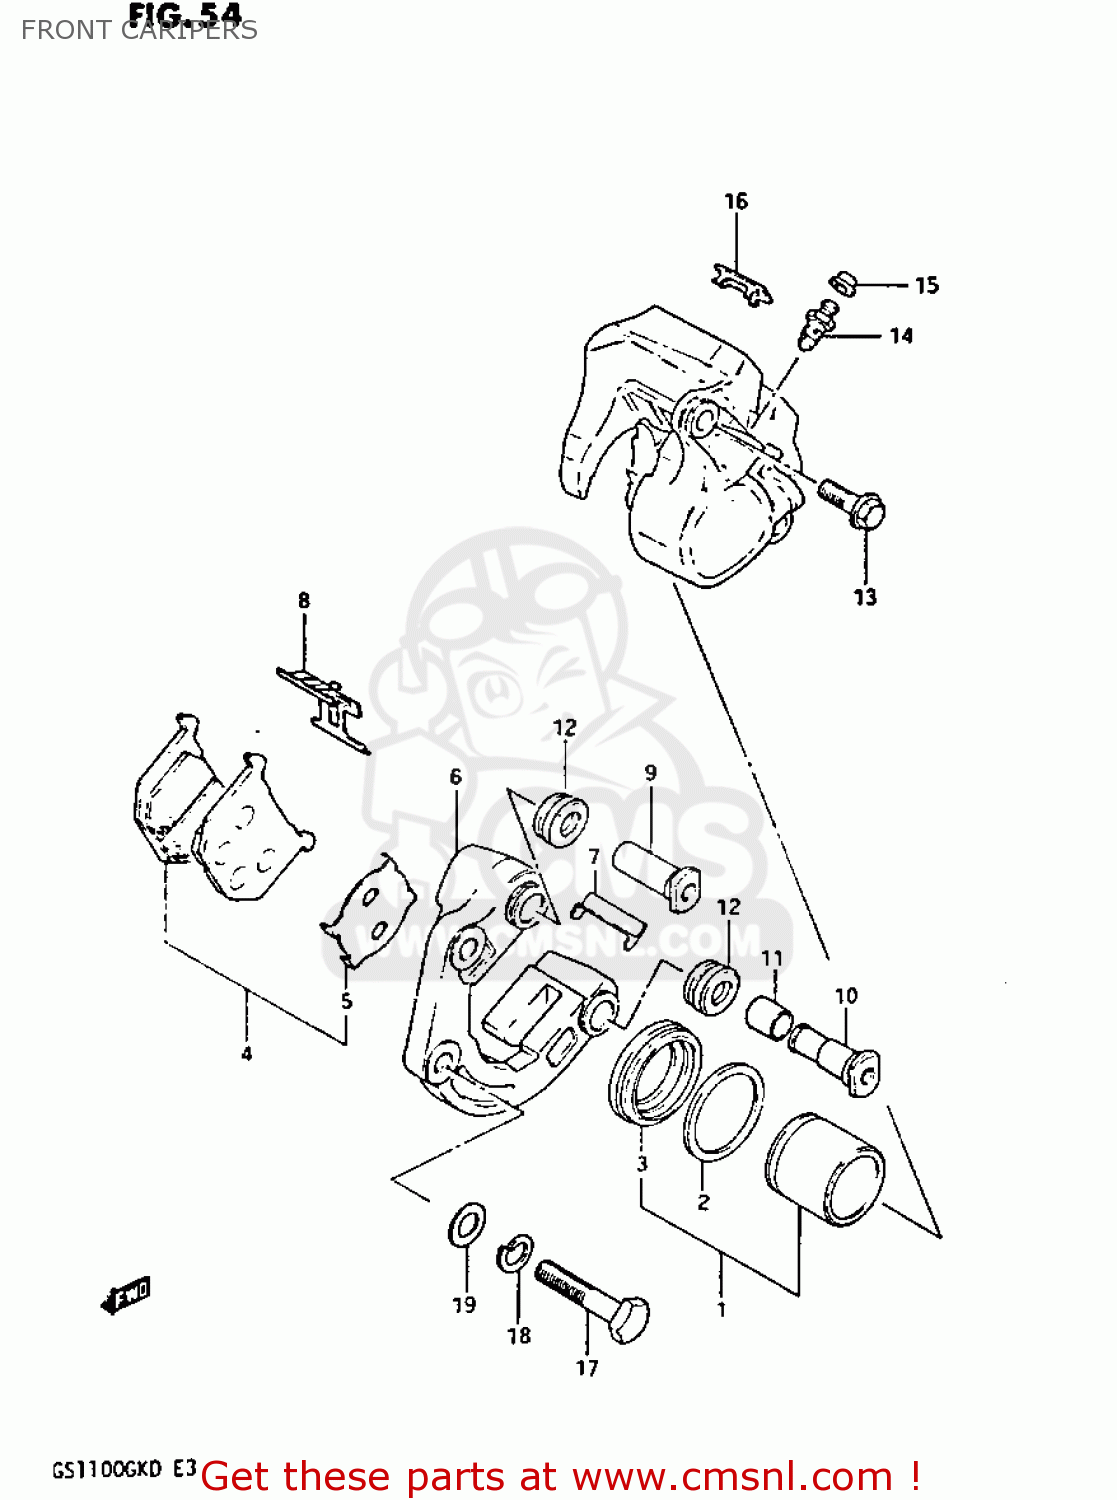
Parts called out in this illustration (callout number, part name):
1	PISTON SET
2	SEAL,FR CALIPE
3	BOOT,PISTON
4	PAD SET,BRAKE (MCA)
5	SHIM,PAD
6	CARRIER,CALIPER,LEFT
7	GUIDE,PAD
8	SPRING,PAD
9	AXLE NO.1
10	AXLE NO.2
11	BUSH,AXLE
12	BOOT,AXLE
13	BOLT
14	BLEEDER
15	CAP,BREATHER
16	COVER
17	BOLT 10X53.5
18	WASHER,LOCK,10
19	WASHER
